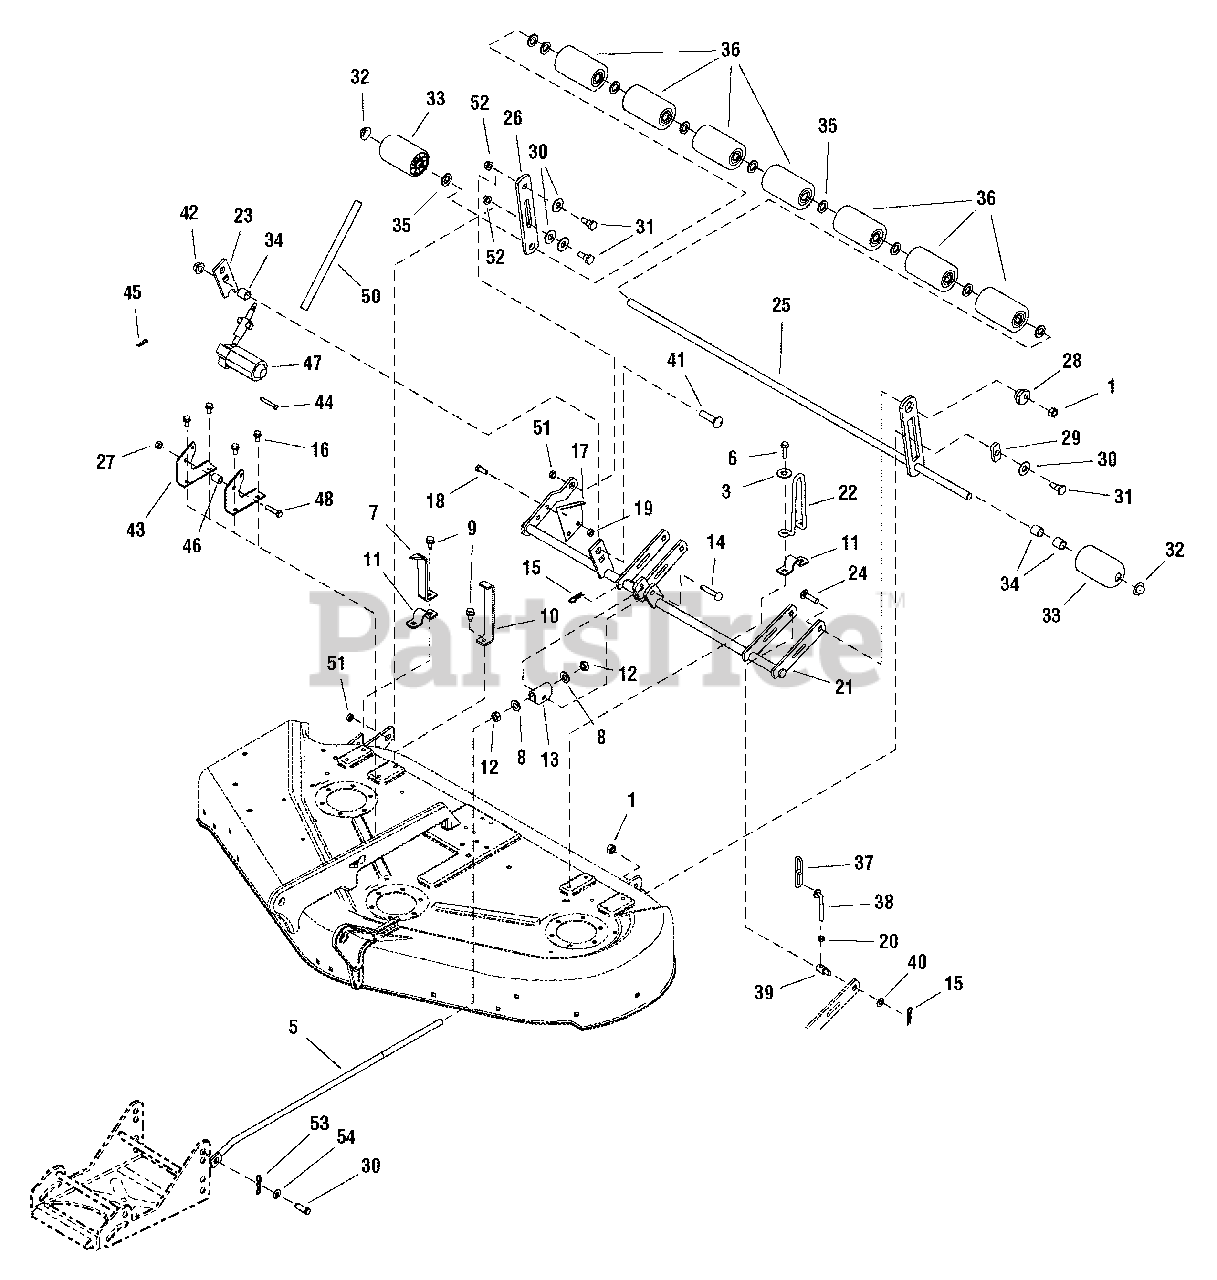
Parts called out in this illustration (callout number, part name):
1	LOCKNUT, Security 3/8-16
3	WASHER, 3/8
5	ROD, Adjustment
6	SCREW, Hex Washer Head Taptite 5/16-18 x 1-1/4
7	INDICATOR, Height of Cut
8	WASHER, 1/2
9	SCREW, Hex Washer Head Taptite 5/16-18 x 3/4
10	BRACKET, Up-Stop
11	STRAP, Roller E-Coat
12	NUT, Hex Jam 1/2-13
13	TRUNNION, Rod
14	PIN, Round Head Drilled 3/8 x 2
15	CLIP, Hair Pin
16	SCREW, Hex Washer Head Taptite 5/16-18 x 5/8
17	BRACKET, Height of Cut 16GA
18	SCREW, Hex Whiz Lock Flange 5/16-18 x 3/4
19	NUT, Hex Flange 5/16-18 Whiz Lock Small
20	NUT, Hex Jam 5/16-18
21	SHAFT ASSEMBLY, Rocker 44"
22	UP-STOP, 6-1/4 High
23	ARM, Rear 1/2 Thick
24	CARRIAGE BOLT, 3/8-16 x 1-1/2 G5
25	SHAFT & BAR ASSEMBLY, Roller 44"
26	BAR, Roller 5/16
27	NUT, Hex Flange 5/16-18 Whiz Lock Large
28	NUT, Hex Adjusting, .99 DIA .687
30	WASHER, 1/2 x 1-1/2 OD
31	BOLT, Shoulder, 3/8-16 X 1.34
32	NUT, Push for 5/8 Diameter Stud Capped
34	SPACER, .66 ID
35	WASHER, 5/8
37	CHAIN, Link
38	ROD, Height Adjusting 5/16-18
40	WASHER, 3/8
41	CARRIAGE BOLT, 1/2-13 x 2 G5
42	NUT, Hex Toplock Flange 1/2-13
43	BRACKET, Mounting 10GA
44	PIN, Shear
45	CLIP, Hairpin
47	MOTOR, Electric
48	CAPSCREW, Hex Head 5/16-18 x 1-3/4 G5
50	TUBE, Flexible
52	NUT, Hex Flange 3/8-16 Machine Lock Large
53	PIN, Cotter Locking
54	PIN, Yoke
